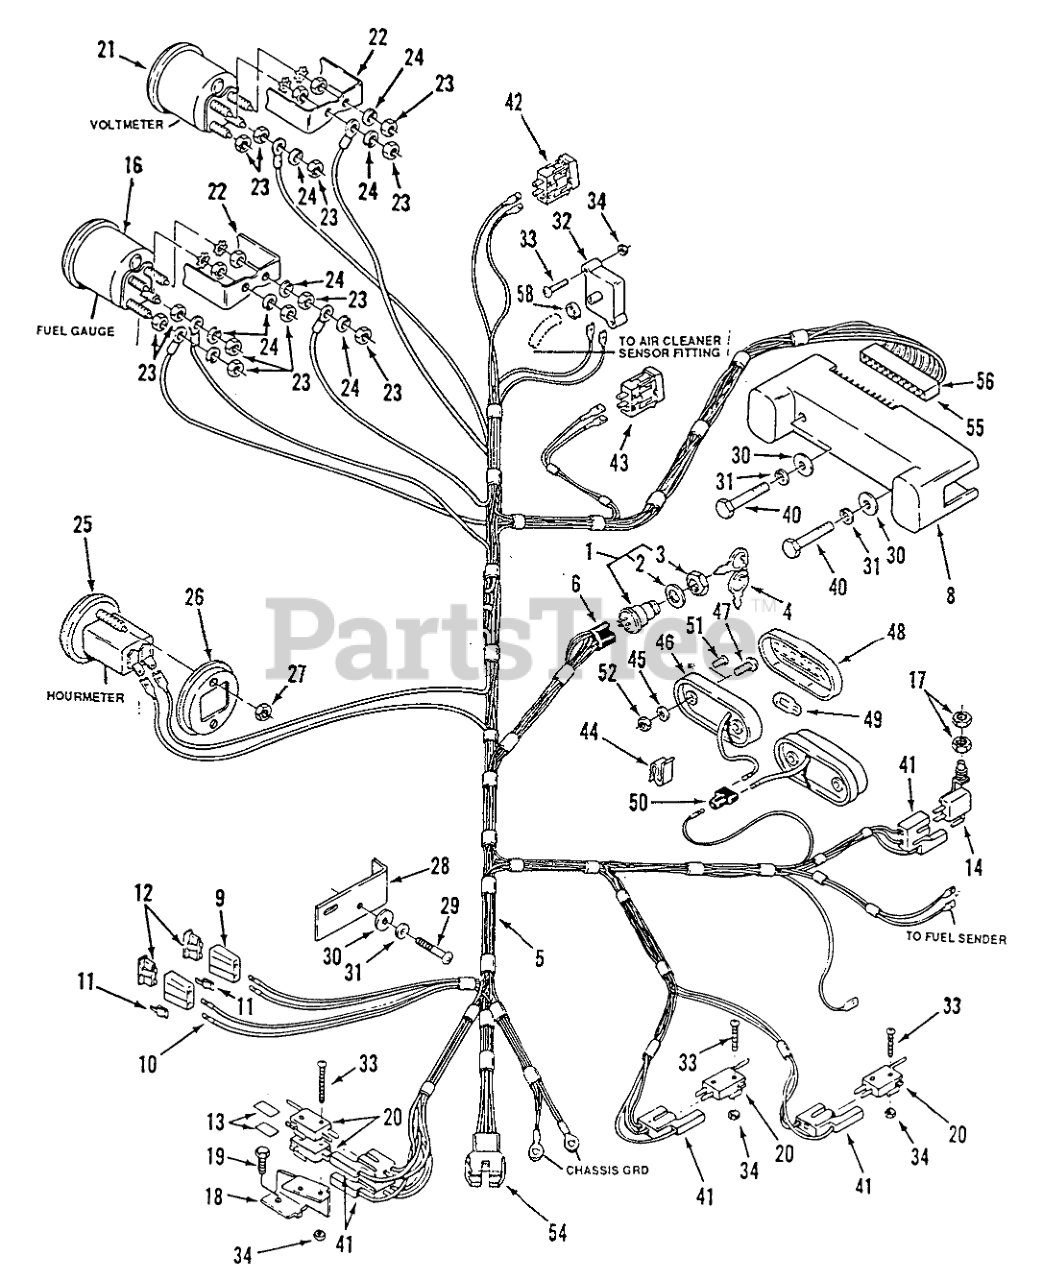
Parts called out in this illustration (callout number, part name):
1	IGNITION SWITCH ASM
2	LOCKWASHER
3	NUT BEZEL
4	Ignition Key
5	WIRING-HARNESS
6	CONNECTOR-5 WAY-SERV
8	6-Light Circuit Module
9	AUTO-FUSEBLOCK TERM
10	TERMINAL FUSE
12	Fuse 10 Amp-ATO or ATC
13	BARRIER - SWITCH
14	Seat Switch
16	Fuel Gauge (includes item 22) All models
17	NUT-HEX, SPECIAL
18	BRACKET-SWITCH
18	RECEPTACLE TERMINAL
19	Bolt
20	SWITCH
21	Voltmeter (includes item 22)
22	BRKT-GAUGE MOUNTING
23	Nut
24	Lockwasher
25	Hourmeter (includes item 26) 518 & 520-s
26	BRKT-GAUGE MOUNTING
27	Hex Nut
28	Light Bracket 516
29	SCREW-PHCR #8-32X.75
30	WASHER
31	LOCKWASHER
32	SENSOR-AIR CLEANER
33	Screw
34	NUT HEX 4-40 ELAST
40	SCREW
41	CONNECTOR BODY
42	Light Switch
43	SWITCH-TEST
44	SPEED CLIP
45	Lockwasher
46	BASE-TAIL LIGHT
47	Screw
48	LENS-TAIL LIGHT
49	LIGHT BULB
50	CONNECTOR 3 WIRE
51	RIVET-4
52	Nut
53	WASHER
54	9-CIRCUIT CAP
55	Connector-Male
56	Terminal
58	Clamp 5/16
59	Wire-Switch to Engine
